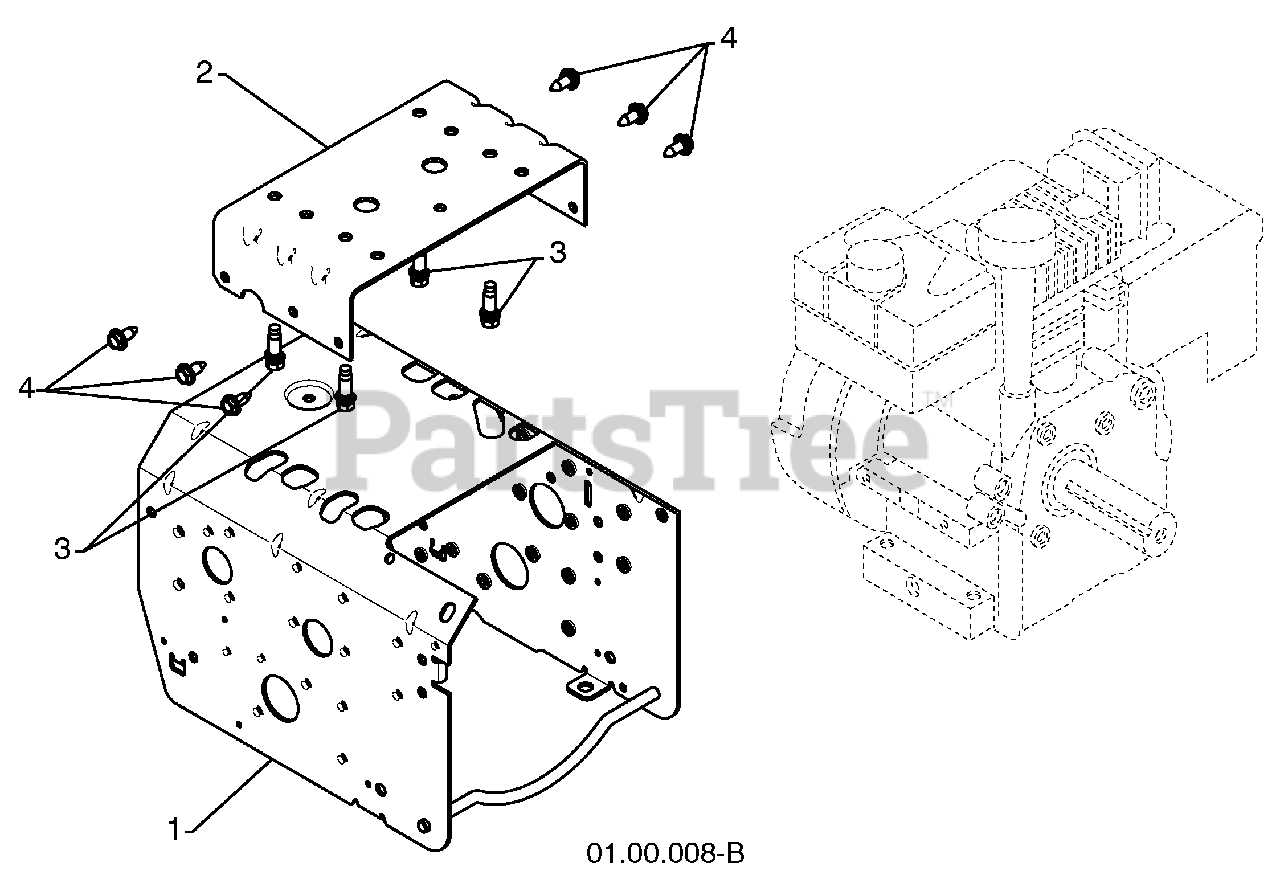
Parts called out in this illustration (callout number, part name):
1	FRAME
2	ENGINE MOUNT PLATE
3	BOLT 3/8-16
4	SCREW 5/16-18 X .750
